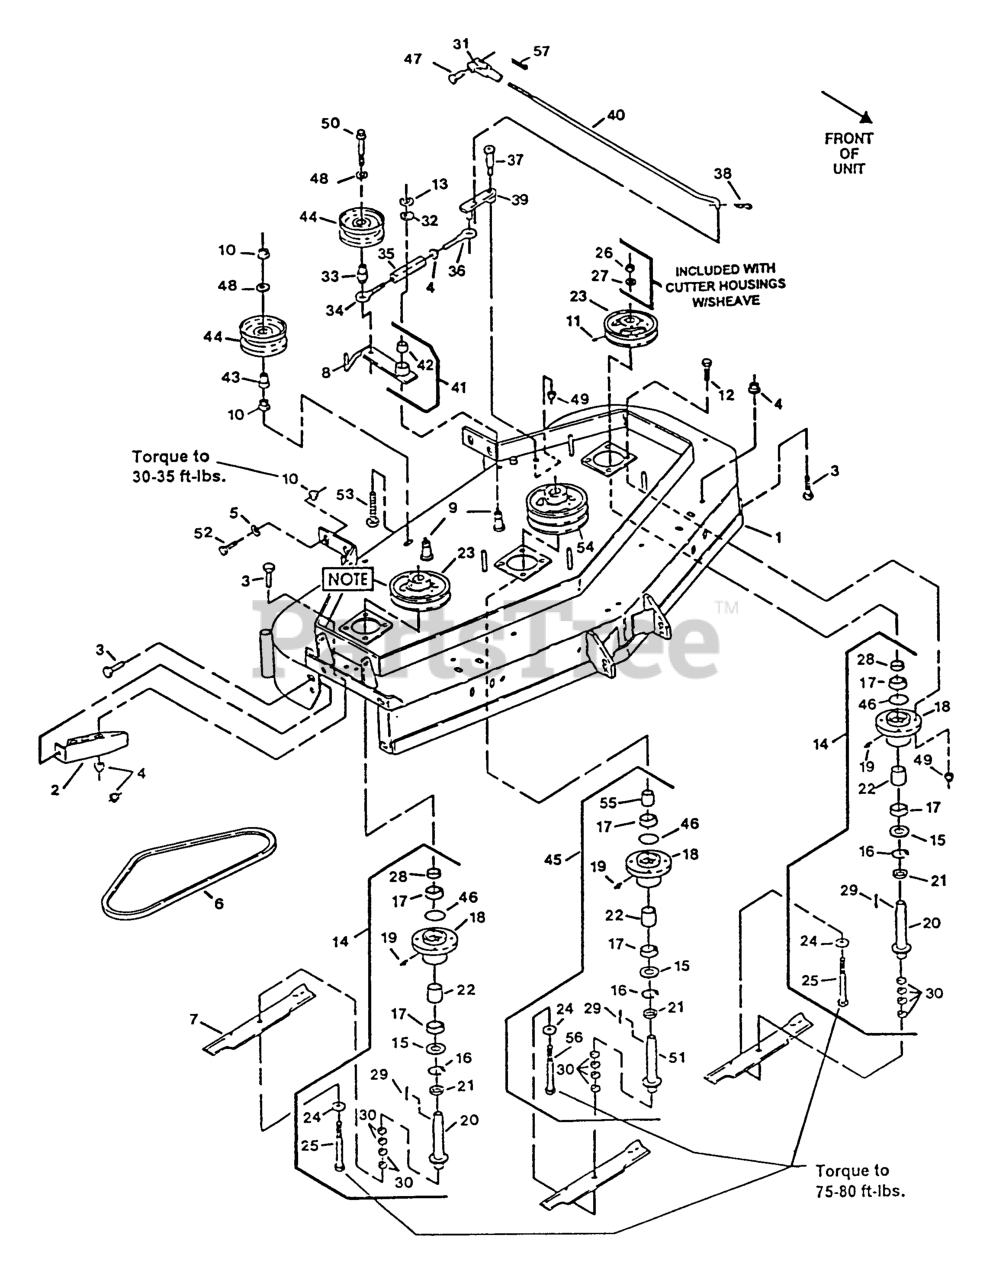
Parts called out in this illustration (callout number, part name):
2	WLD, DISCHARGE BAFFLE
11	SCREW-SET
14	ASM,HOUSING CUTTER
15	SEAL,DUST
16	RING,SNAP WLDS N5000-244
17	BEARING,HD SPINDLE
18	HOUSING,CUTTER
21	SPACER,BEARING &SPINDLE
22	SPACER,BRG/BRG
24	WASHER-SPRING
25	SCREW-CAP, HH
27	WASHER-RETAINER, SHEAVE
31	YOKE-ADJUSTABLE
32	WASHER-SPINDLE
33	BUSHING-ENGAGEMENT
34	EYEBOLT-THREAD, LH
35	BODY-TURNBUCKLE
36	EYEBOLT-THREAD, RH
37	BOLT,SHLDR KSKH
38	PIN-COTTER
40	LINKAGE
42	BEARING,POWDERED METAL
43	BUSHING,IDLER
47	PIN-CLEVIS
53	BOLT,TAP HH3/8-16X2-1/4
55	SPACER,BEARING/SHEAVE
56	SCRW,CAP HH 5/8-18X8.5
